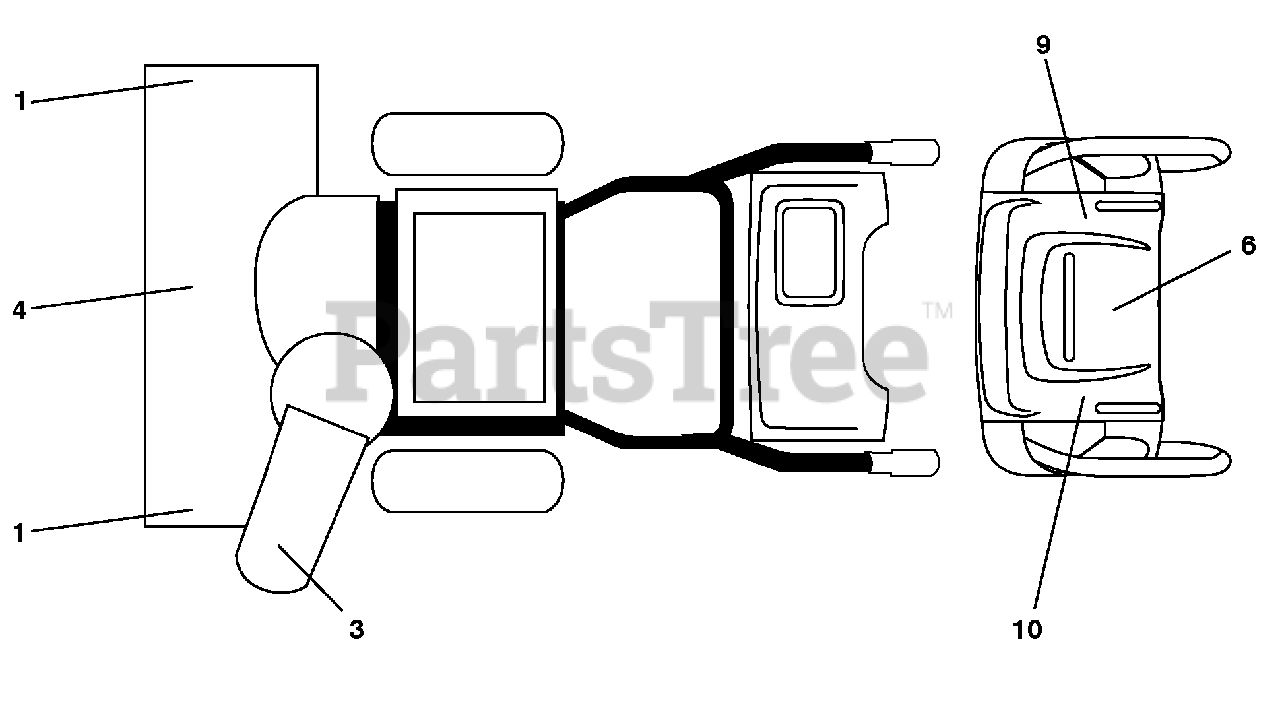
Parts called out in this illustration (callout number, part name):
1	DECAL, DANGER
3	DECAL, DANGER, DEFLECTOR
4	DECAL, DANGER
6	DECAL, INSTRUCTION
9	DECAL, CONSOLE RT, SPEED LEVER, POWERSTEERING
10	DECAL, CONSOLE LT, SPEED LEVER, POWERSTEERING
